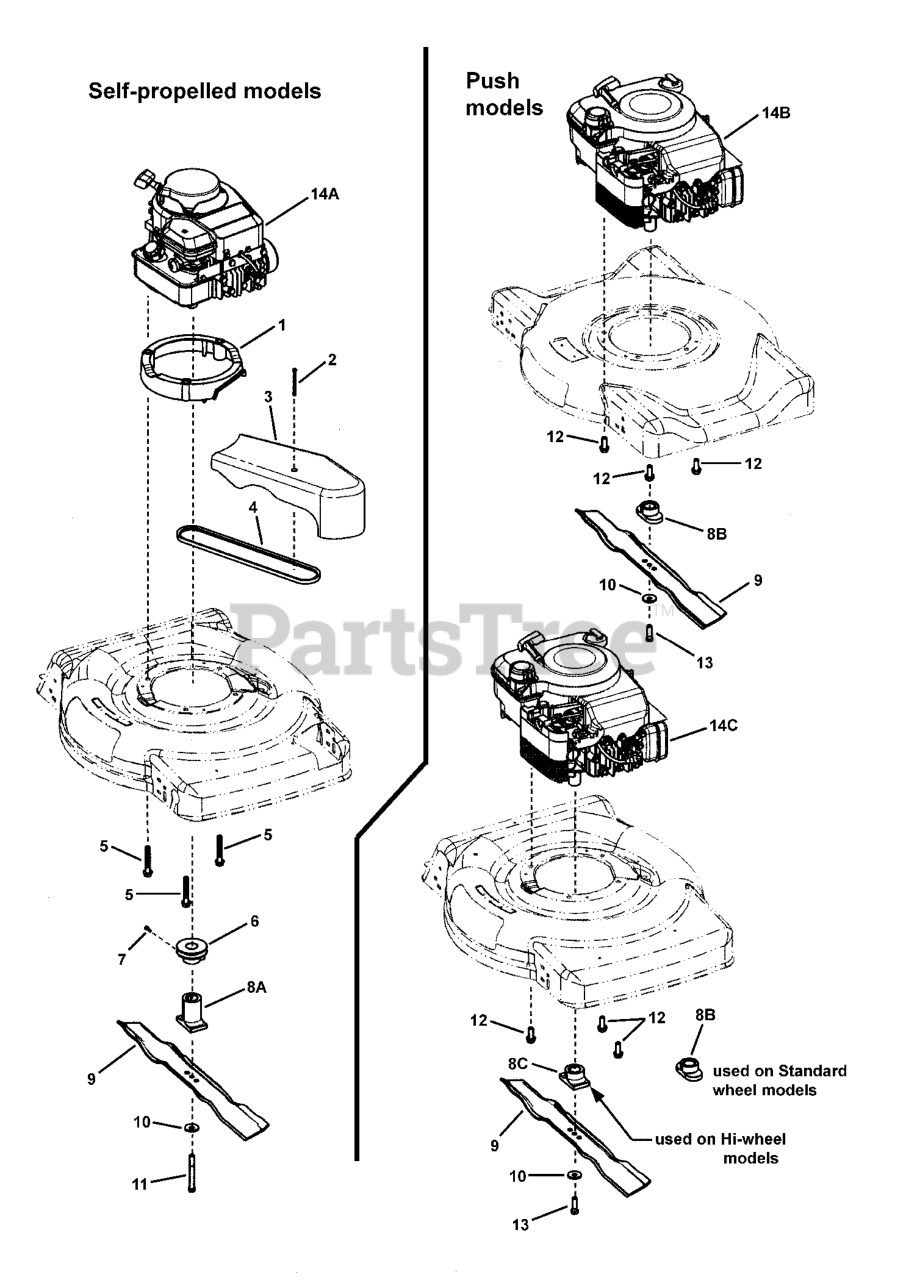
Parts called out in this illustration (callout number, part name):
1	** ASSY, Engine Spacer, 22" WBM, Propelled
2	SCREW, #10-24 x 2-1/2"
3	COVER, Belt, Plastic
4	BELT, Drive 22" WBM, SS (3L sect. 33.75 effective length)
5	BOLT, 3/8-16 x 2-1/2" Hex Washer Face
6	PULLEY, Engine, 22" Deck, Single Speed
7	SCREW, #8-11 x 5/8" Poly
8A	HUB, Blade, 22" Deck (self-propelled)
8B	HUB, Blade, 22" Push
8C	HUB, Blade, 22" Push
9	BLADE, 22" Walk Mower
10	WASHER, Bellville, .38" ID x 1.183 OD
11	BOLT, 3/8-24 x 3-1/4" Hex Head, GR 8
12	SCREW, 3/8-16 x 1" Hex Washer Self-Tap
13	SCREW, 3/8-24 x 1-1/4" Hex Head Cap, GR 5
14A	* ENGINE, B&S, 650 Ser, B3, X-Spec
14A	* ENGINE, B&S, 650 Ser, B1, X-Spec
14A	* ENGINE, B&S, 650 Ser, F3, X-Spec
14A	* ENGINE, B&S, 675 Ser, B3, X-Spec
14A	* ENGINE, B&S, 675 Ser, F3, X-Spec
14A	* ENGINE, B&S, 675 Ser, X-Spec, B1, FC
14B	* ENGINE, B&S, 500 Ser, Murray, XSQ, B1
14B	* ENGINE, B&S 500 Series, FC
14C	* ENGINE, B&S, 550 Ser, X, B3
14C	* ENGINE, B&S, 550 Ser, XAQ, B1
14C	* ENGINE, B&S, 550 Ser, FC, B1
